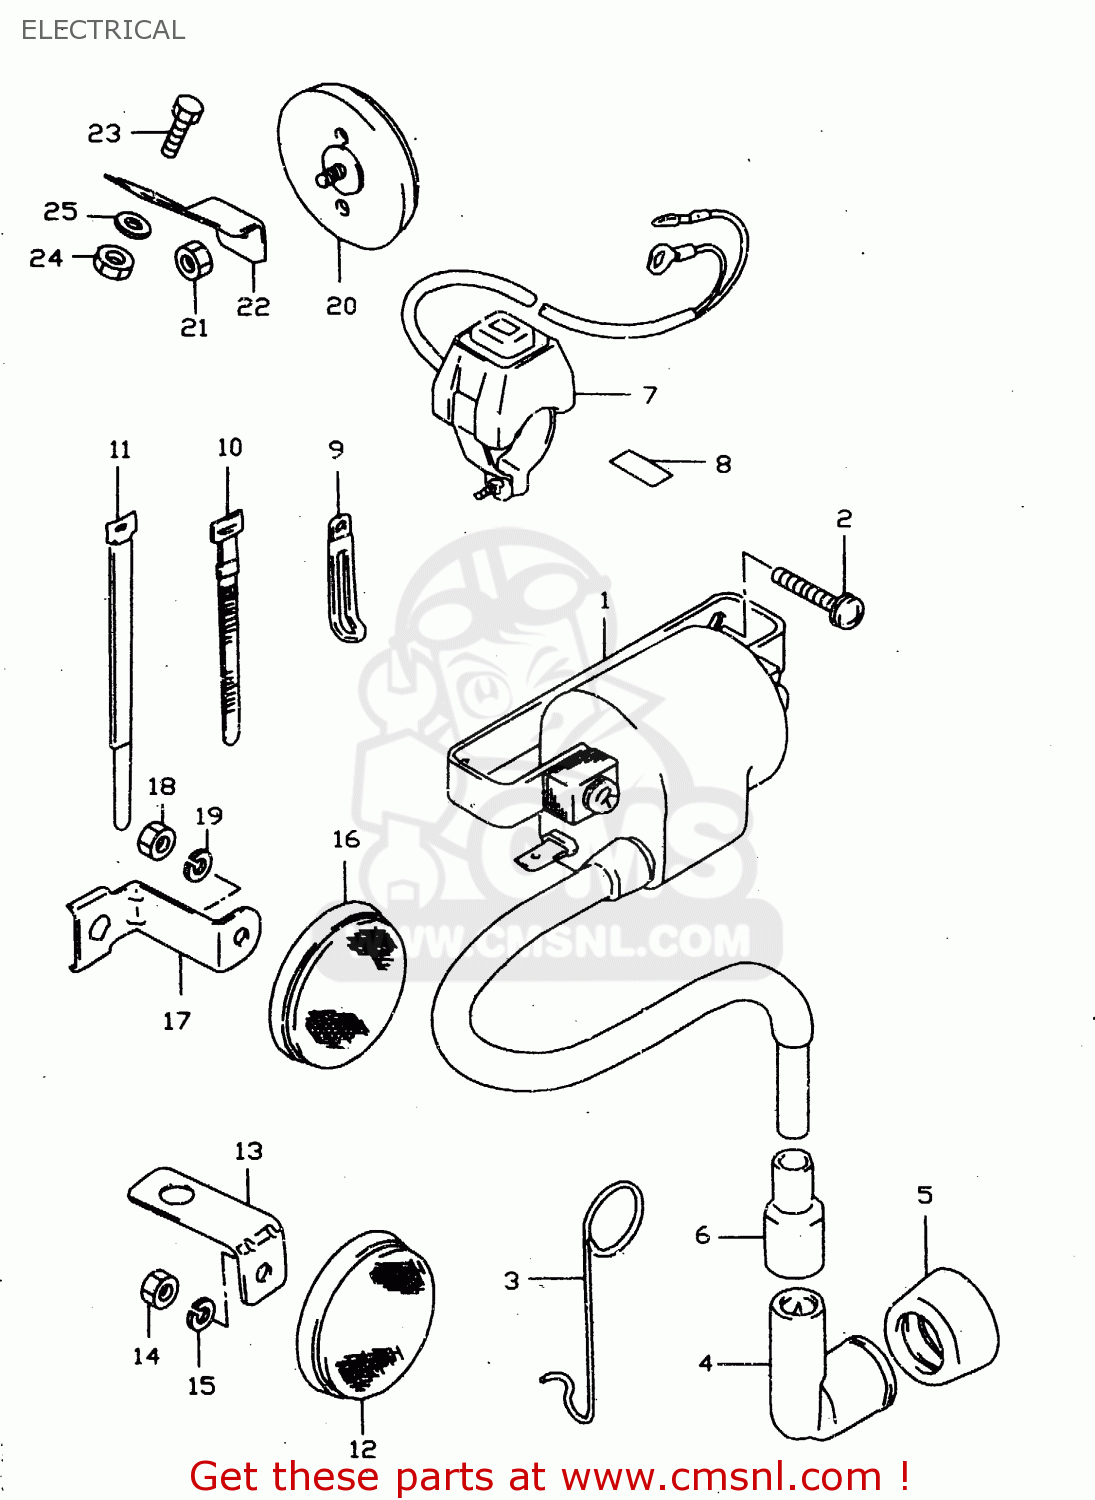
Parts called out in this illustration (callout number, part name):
1	UNIT & COIL ASSY,IGNITION
2	SCREW
3	CLIP
4	CAP ASSY,SPARK PLUG
5	SEAL,SPARK PLUG
6	SEAL,HIGH TENSION CORD
7	SWITCH ASSY,ENGINE STOP
8	LABEL (ENGINE STOP)
9	CLAMP(L:45)
10	CLAMP(L:120)
11	CLAMP
12	REFLEX REFLECTOR,FR
13	BRACKET, FR SIDE RR
14	NUT
15	LOCK,WASHER
16	REFLEX REFLECTOR,RR
17	BRACKET, NEAR SIDE RR
18	NUT
19	LOCK,WASHER
20	REFLEX REFLECTOR,RR
21	NUT
22	BRACKET, NEAR RR
23	BOLT
24	NUT 6MM
25	WASHER
